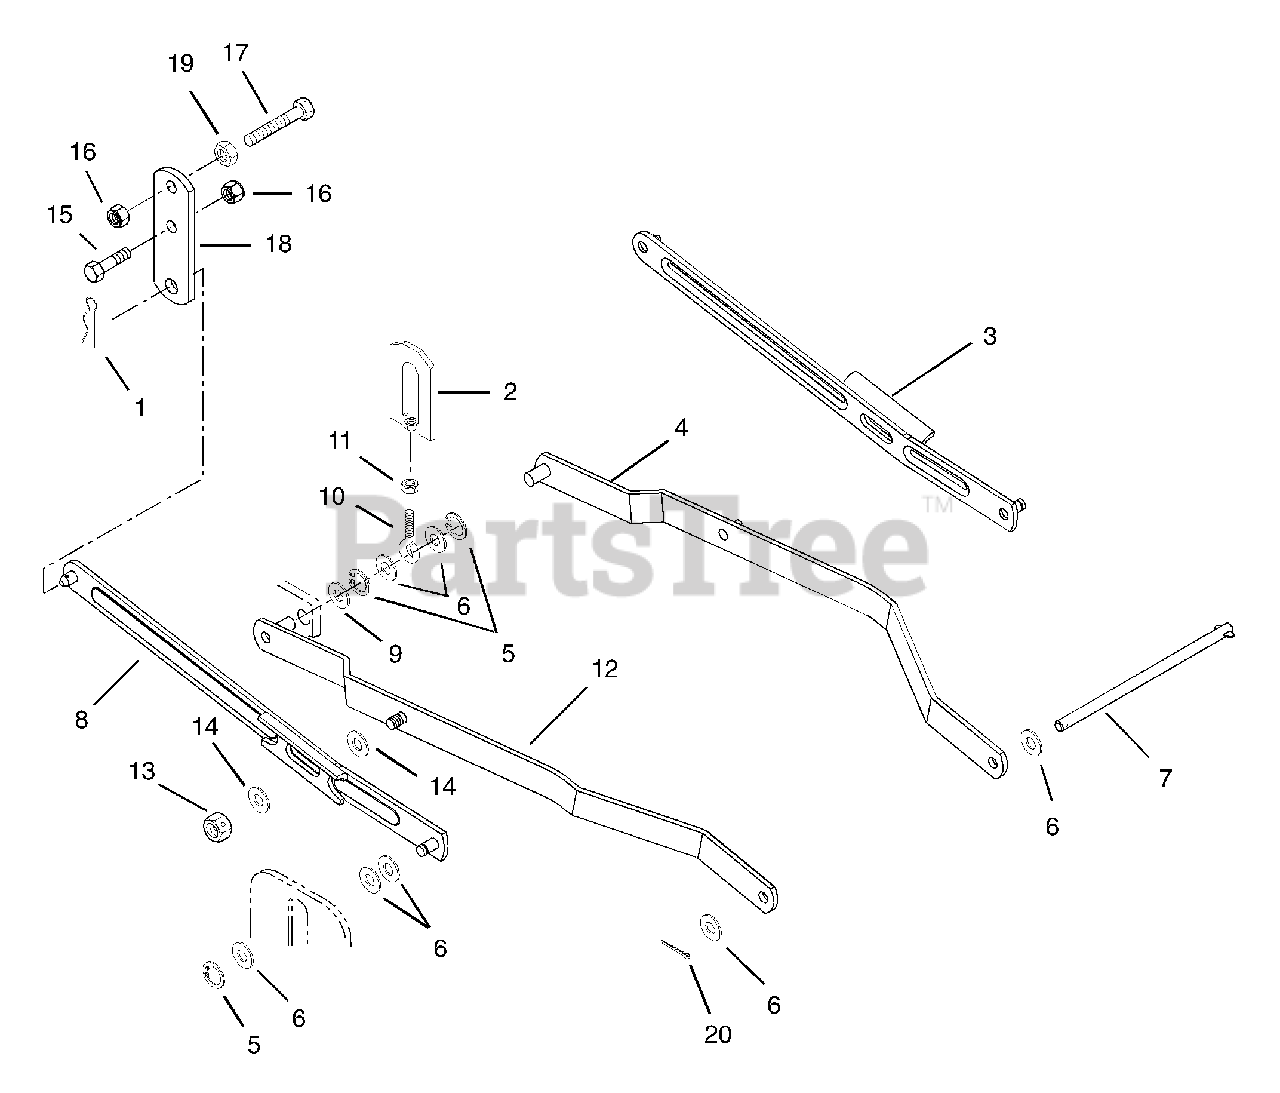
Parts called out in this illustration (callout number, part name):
1	PIN-HAIR-EXT .12X.31X2.37 YWZC
2	LINK, ADJUSTMENT
3	REAR HANGER, L.H.
4	L.H. LIFT ARM
5	RG-RTNG-EXT .500X.050 (SNAP)
6	@WSHR-FL-STL.531X1.06X.095YWZC
8	REAR HANGER, R.H.
9	@WSHR-FL-STL.531X1.06X.095YWZC
11	NUT-HEX-JAM .375-16 YWZC
12	R.H. LIFT ARM
13	@NUT-LK-CTR .62-11 YWZC
14	@WSHR-FL-STL.656X1.31X.095 YWZ
15	@BLT-HEX .38-16X.75 GR5 YWZC
16	@NUT-LK-CTR .38-16 YWZC
17	@BLT-HEX .38-16X1.75 GR5 YWZC
18	HANGER BRACKET
19	@NUT-HEX .38-16 YWZC
20	@PIN-CTR .12X1.00 EXTPRSQCT YZ
